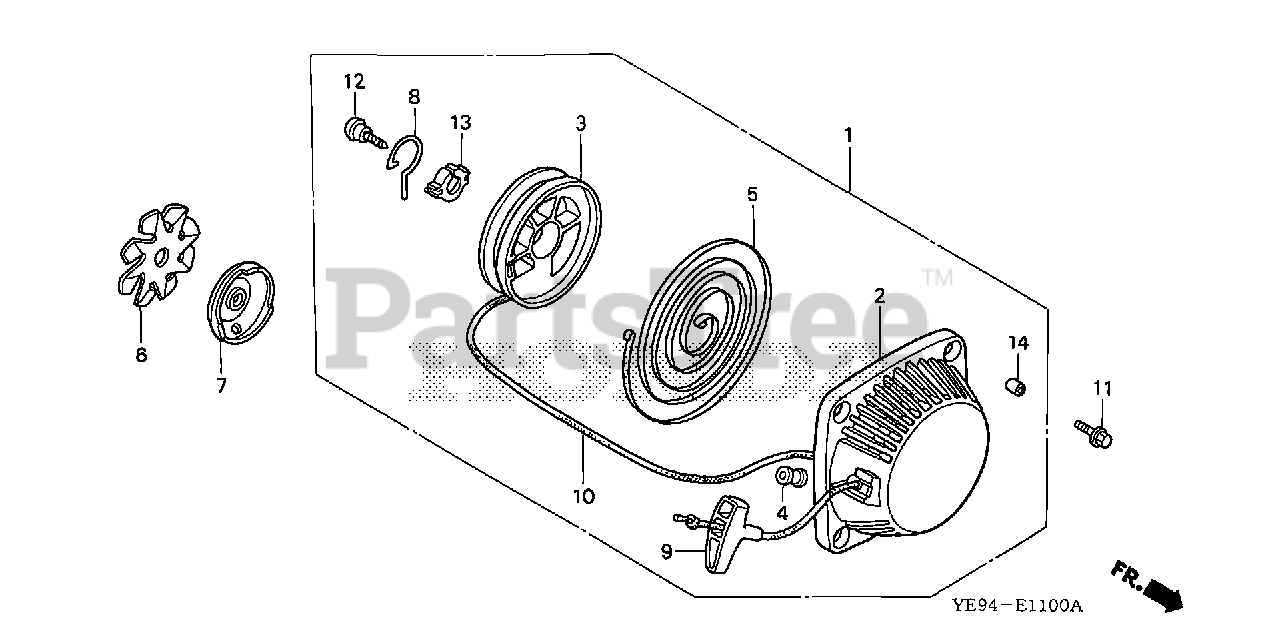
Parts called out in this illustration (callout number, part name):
1	STARTER ASSY., RECOIL *NH1* (BLACK)
2	CASE, RECOIL STARTER
3	REEL, RECOIL STARTER
4	GUIDE, ROPE
5	SPRING, RECOIL STARTER
6	FAN, RATCHET
7	PULLEY, RECOIL STARTER
9	KNOB, RECOIL STARTER
10	ROPE, RECOIL STARTER
11	BOLT, FLANGE (5X18)
12	SCREW, SETTING
